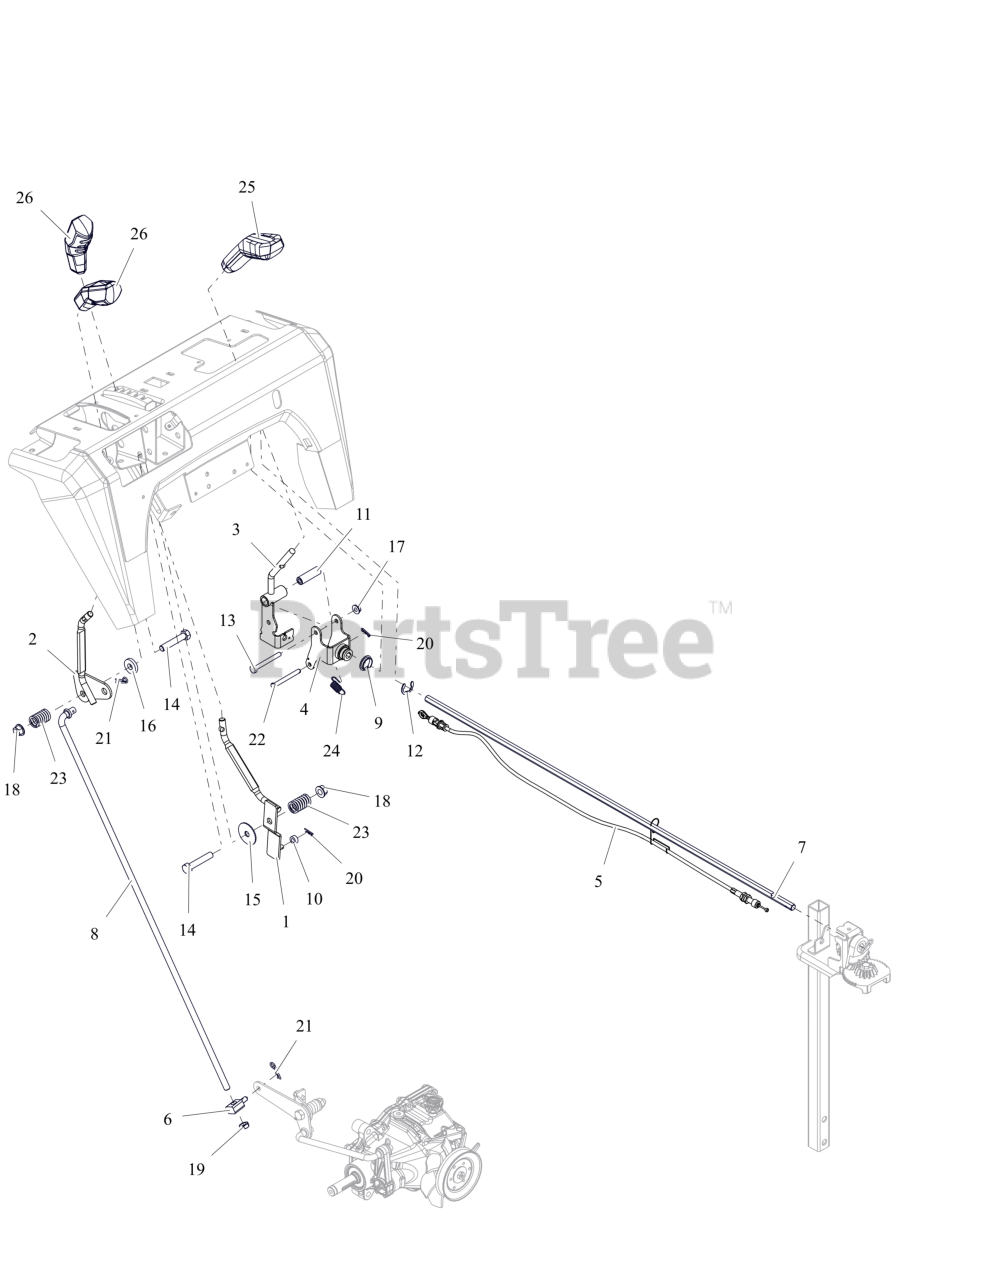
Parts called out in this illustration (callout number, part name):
1	WELDMENT,LG DASH DEFL CONTROL
2	WELDMENT,LG DASH SPEED CONTROL
3	WELDMENT, CONTROL LEVER
4	WELDMENT, CONTROL BRACKET
5	CABLE, CHUTE LOCK, PRO
6	PIVOT,SHIFT ROD .375-16(TRUNN)
7	ROD, HEX - CHUTE ROTATION
8	ROD, SHIFT - PRO
9	BUSHING, POLYLINER-.75 SNAPIN
10	BSHG-SLV .265X.500X.219
11	BSHG, SLV .265X.505X1.665
12	E-RING .750X.050
13	BLT,HEX .25-20X2.25 G5 ZCC
14	BLT,HEX .38-16X2.00 G5 ZCC
15	WSHR,FLT .380X1.50X.062 ZCC
16	WSHR, FLT .406X1.00X.188 ZCC
17	NUT-LK-CTR-FLG .25-20 ZC120
18	NUT-LK-TOP-FLG .38-16 ZC120
19	NUT-JAM .375-16 G2 ZCC
20	PIN, HAIR #178 .06X.77 ZCC
21	PIN, HAIR #213 .08X1.19 ZCC
22	PIN, CLEVIS - .25 X 2.25 ZCC
23	SG-COMP .125X.781X1.250
24	SPRING-EXT .047X.438X1.45
25	HANDLE, QUICK TURN
26	KNOB, CONTROL
